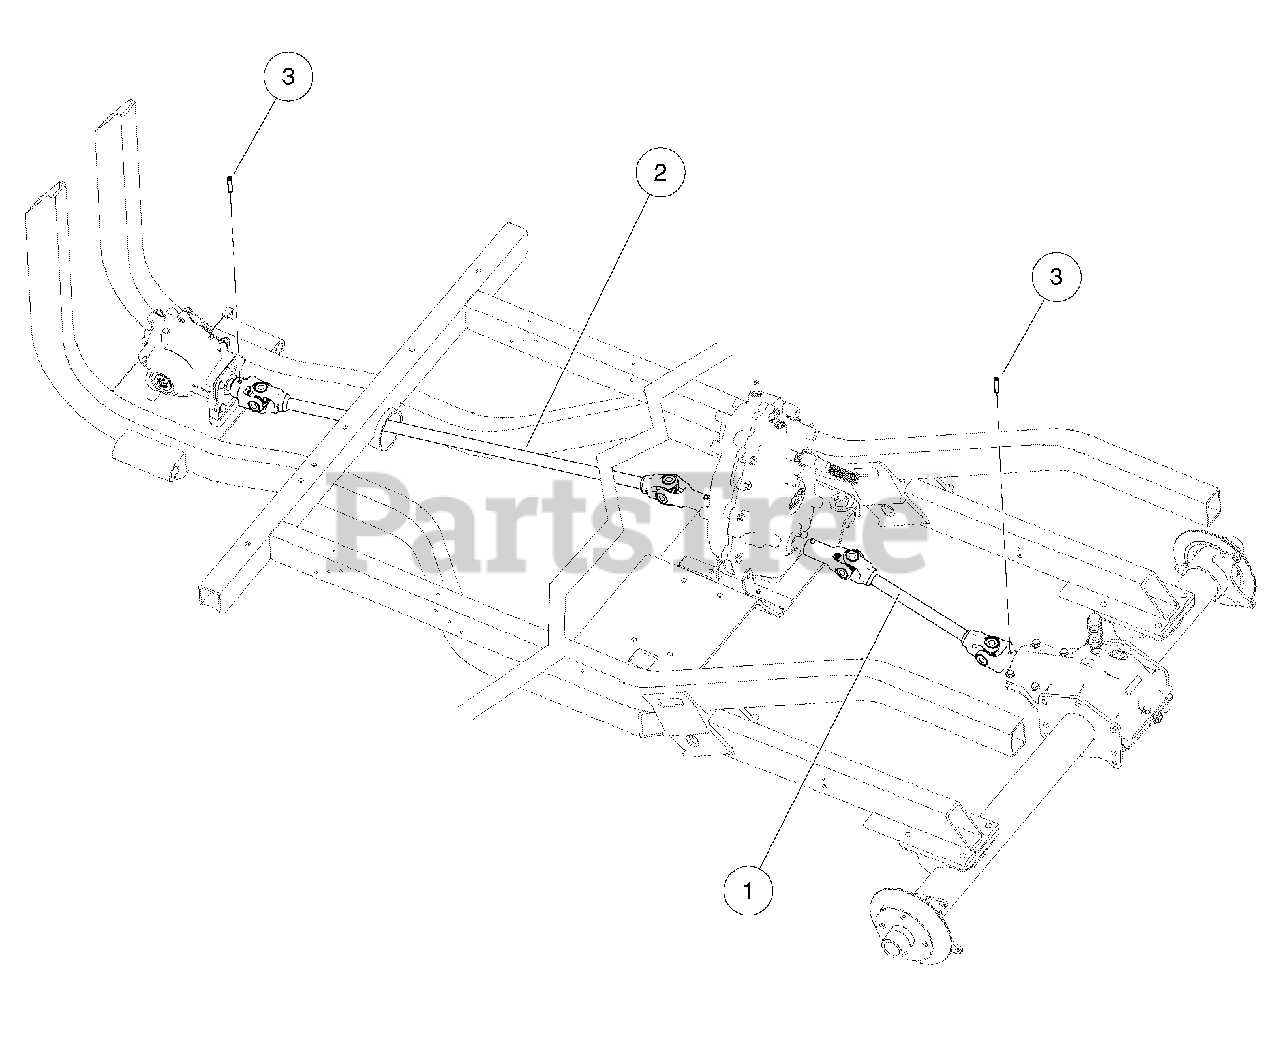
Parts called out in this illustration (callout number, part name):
1	Prop Shaft, Rear
2	Prop Shaft, Front, Long
3	Pin, Spring, 5/16 X 1-1/2 Hd
